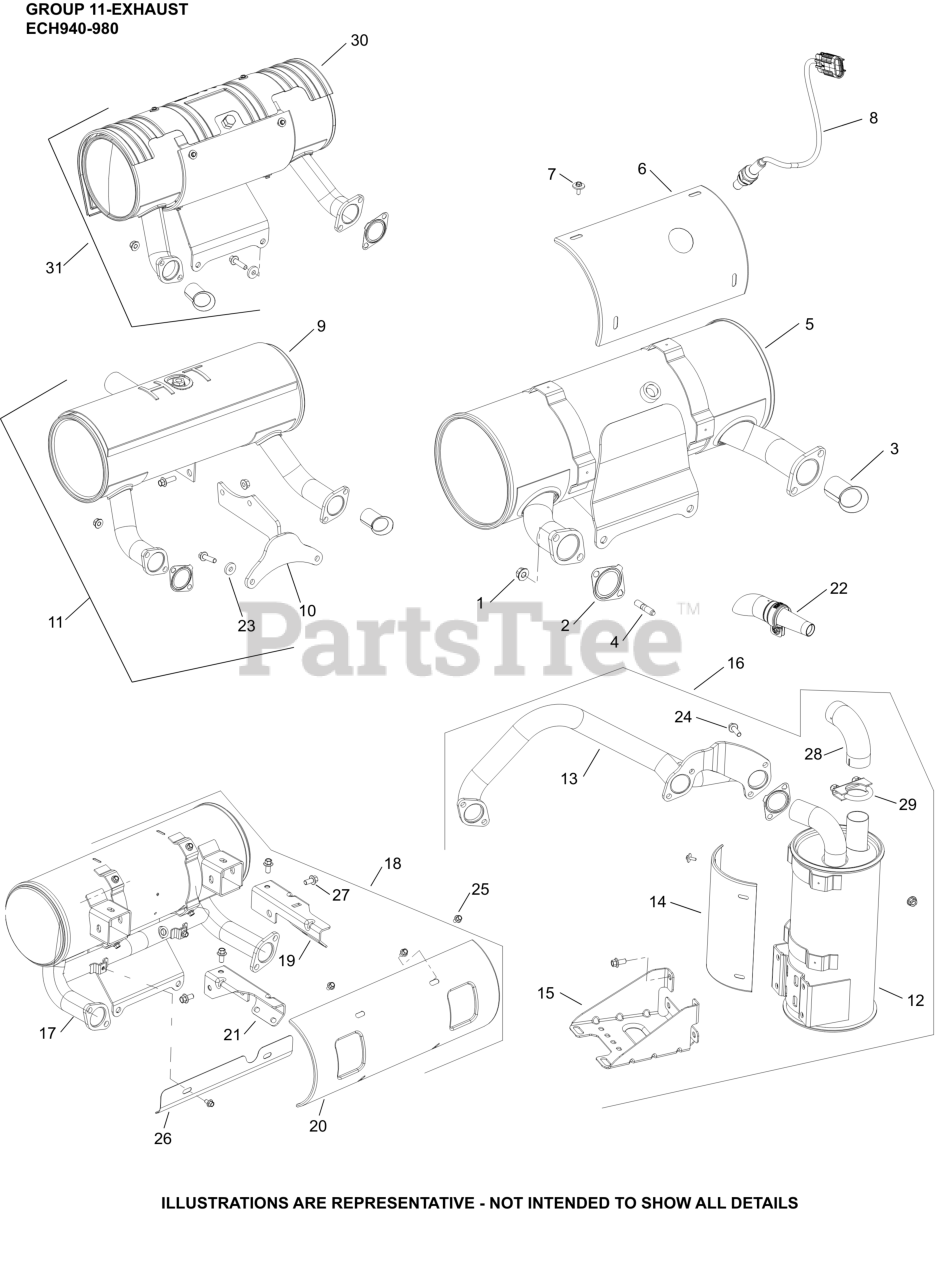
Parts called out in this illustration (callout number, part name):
1	NUT, HEX FLANGE LOCK (M8)
2	GASKET, EXHAUST
3	LINER, EXHAUST PORT
4	STUD, METRIC EXHAUST
5	MUFFLER, HORIZONTAL
6	SHIELD, HEAT (HORIZONTAL)
7	SCREW, SEMS DRILL #8-18X1/2"
8	SENSOR, OXYGEN (M18 x 1.5 THREADS)
